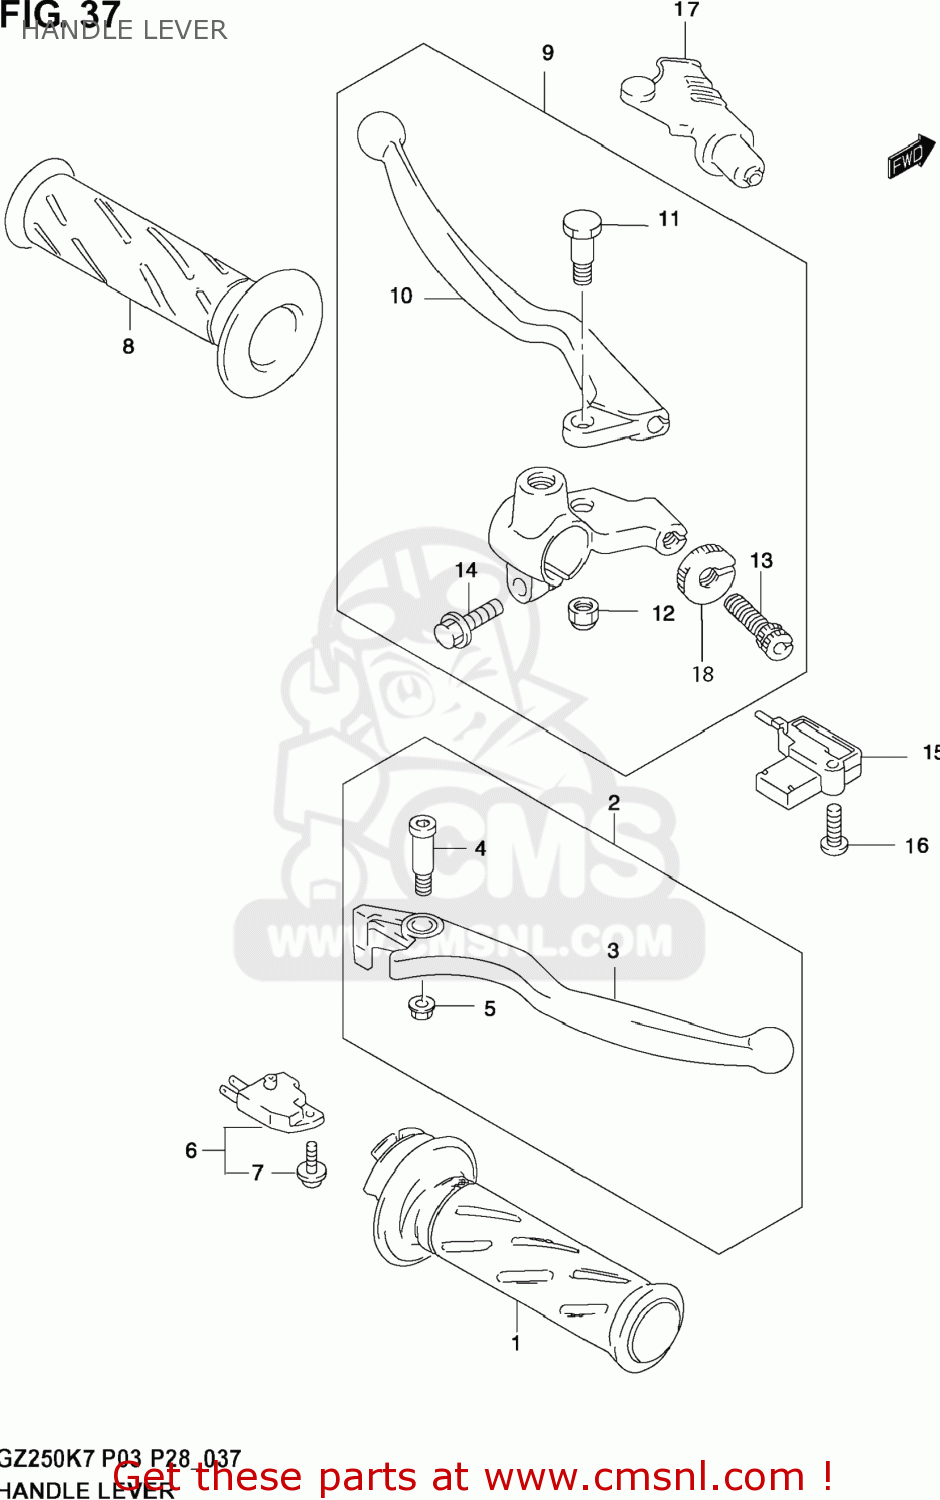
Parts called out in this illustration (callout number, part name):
1	GRIP, THROTTLE
2	LEVER ASSY, BRAKE
3	GRIP, BRAKE
4	BOLT, PIVOT
5	NUT
6	SWITCH ASSEMBLY,STOP
7	SCREW
8	GRIP LH
9	LEVER ASSY, CLUTCH
10	LEVER, CLUTCH
11	BOLT, PIVOT
12	NUT
13	ADJUSTER SET, WIRE
14	BOLT
15	SWITCH,CLUTCH
16	SCREW
17	COVER,CLUTCH LEVER
18	NUT,LOCK
